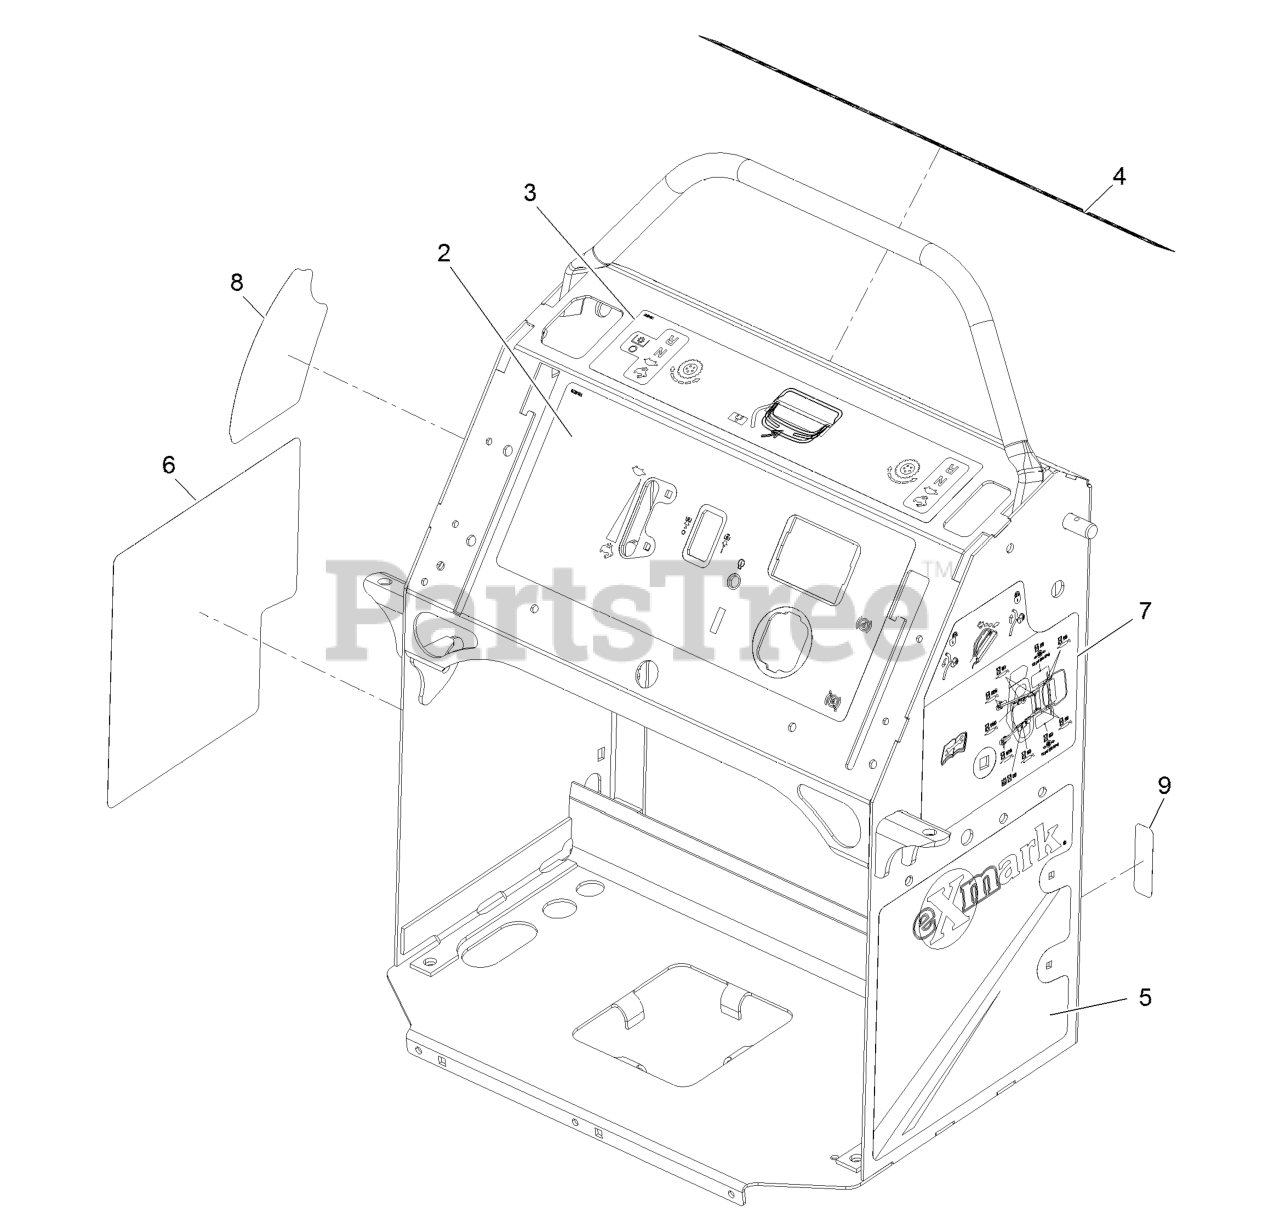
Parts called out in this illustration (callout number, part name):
2	DECAL-CONTROL PANEL EFI
3	DECAL-MOTION CONTROL
4	DECAL-WARNING
5	DECAL-LH PANEL
6	DECAL-RH PANEL
7	DECAL-SERVICE AID
8	DECAL-HEIGHT OF CUT
9	DECAL-FUSE
